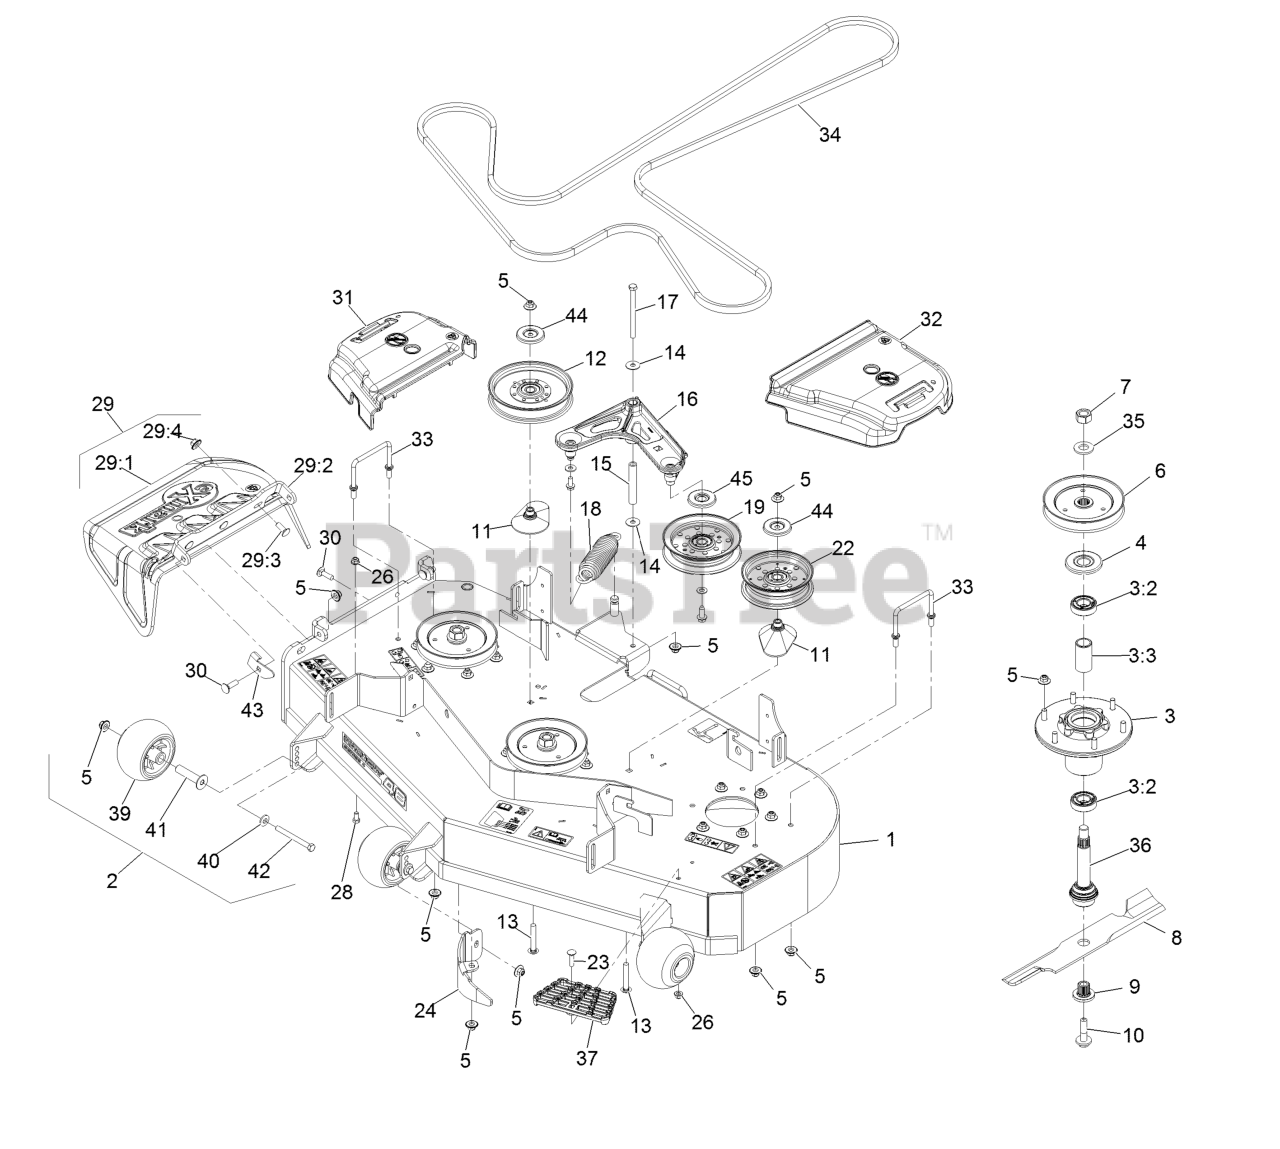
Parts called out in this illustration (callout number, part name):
1	ASM-Deck W/Decals 484
2	Kit, Anti-Scalp Roller
3	ASM-Cutter Hsg With Bearings
3:2	Bearing-Ball
3:3	Spacer-Bearing
4	Guard,Bearing Top .989
5	Nut-Nyloc 3/8-16 Flg
6	Sheave,Blade Drive 5.90
7	Nut-Hex
8	Blade-Extreme 2, 16.25"
8	Blade-Notched
8	Blade, Mulching
8	Blade, Low Lift
8	Blade, Solid
9	Bushing, Splined
10	Screw-Sems 1/2-20 X 2.19
11	Spacer-Pulley
12	Idler-Pulley, Flat 6.00X1.00
13	Bolt-Carriage 3/8-16 X 2 1/2
15	Bushing
16	Idler Arm ASM
17	Screw-HH 3/8-16 X 4 3/4
18	Spring-Extension
19	Idler-Pulley, Flat
22	Idler-Pulley, Flat 5.00X1.31
23	Bolt-Carriage 5/16-18 X 1 1/4
24	Baffle-Dogleg,Lzs Lzx Vt48
26	Nut-Nyloc 5/16-18 Flg
28	Screw-HH 5/16-18 X 5/8
29	ASM,Discharge Chute
29:1	Chute, Discharge
29:2	Bracket,Discharge Chute
29:3	Bolt-Carriage 3/8-16 X 1
29:4	Nut-Nyloc 3/8-16 Flg
30	Bolt-Carriage 3/8-16 X 1 1/4
31	Cover-Belt, RH
32	Cover-Belt, LH
33	Wireform-Cover
34	Belt-V
35	Washer-Spring Disc 3/4
36	ASM-Spindle And Seal
37	Step-Deck
39	Roller-Anti-Scalp
40	Washer-Spring Disc 3/8
41	Axle, Roller
42	Screw-HH 3/8-16 X 3 3/4 GR 8
43	Stop-Discharge Chute
44	Shield-Dust
45	Shield-Guard, Dust
